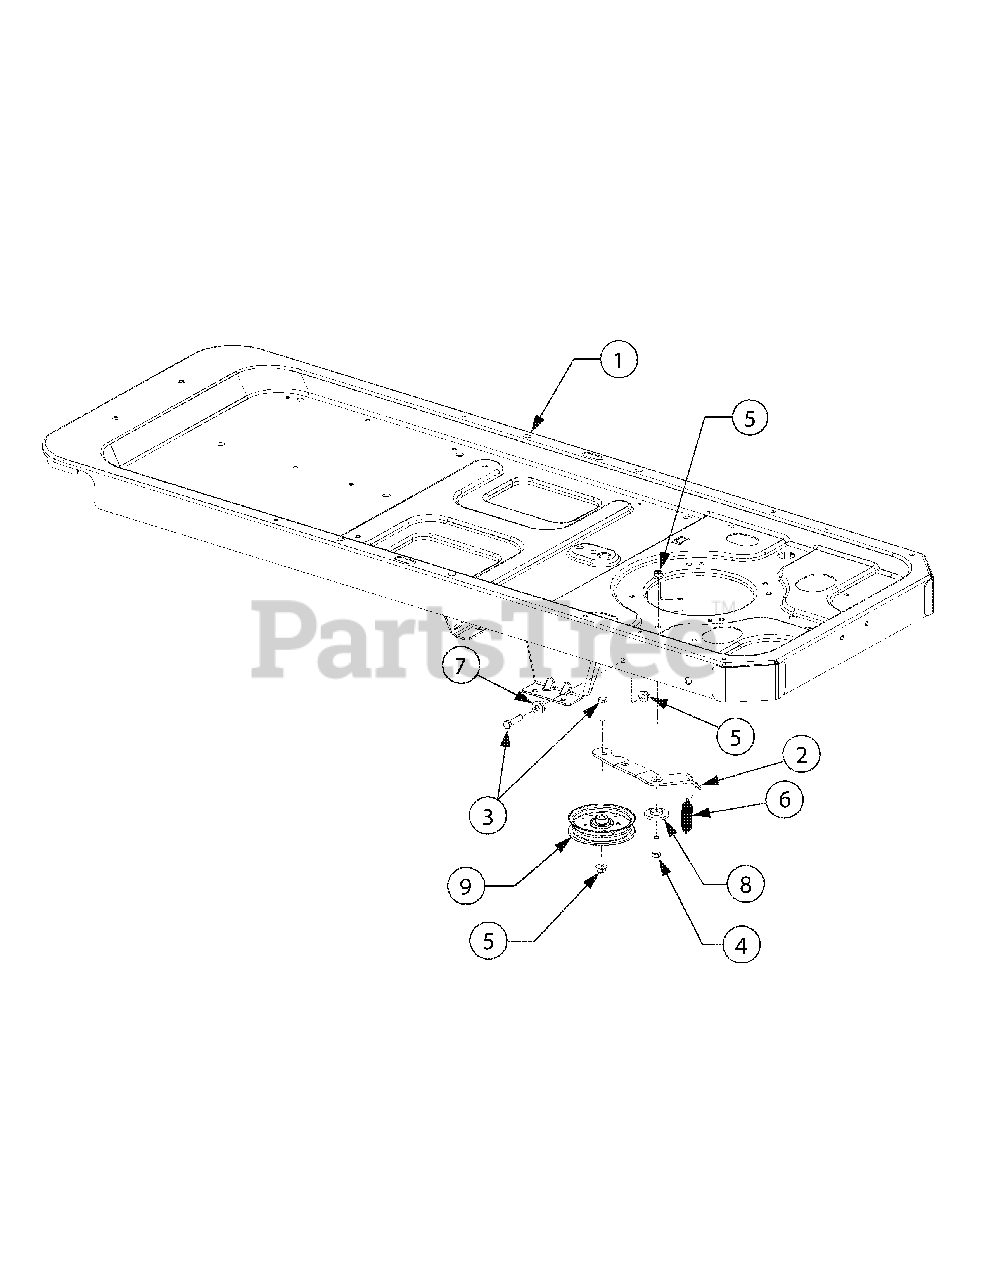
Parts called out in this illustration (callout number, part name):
3	Screw, Hex Cap, 3/8-16 x 1.5 GR5
4	Screw, Hex Cap, 3/8-16 x 1.25 GR5
5	Nut, Hx Insert Flnge Lck, 3/-16 GrF
6	Spring, Extension, .75 x 5.06
7	Spacer, Shoulder, .39 x 1.0 x .7
8	Screw, Shoulder, .884 x .19
9	Pulley, Idler, 4.25 Dia.
